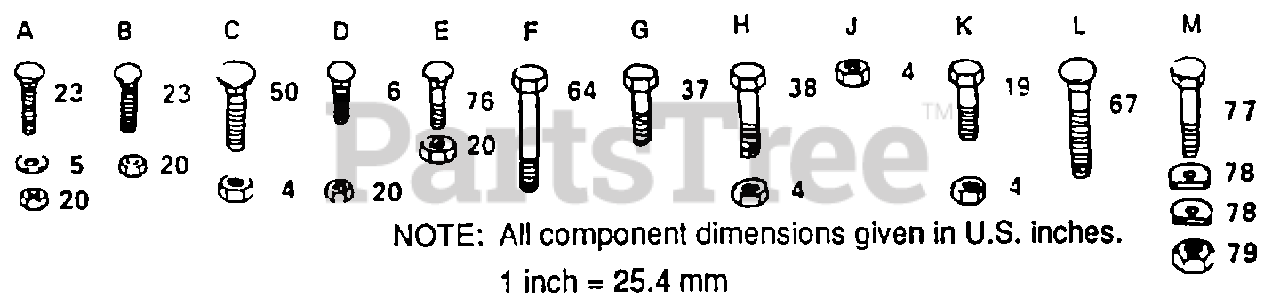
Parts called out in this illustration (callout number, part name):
5	WASHER M
6	BOLT
23	BOLT
37	SCREW
38	SCREW
50	BOLT
64	BOLT
67	BOLT.3/8-14X1.25
77	BOLT LT
78	WASHER T
